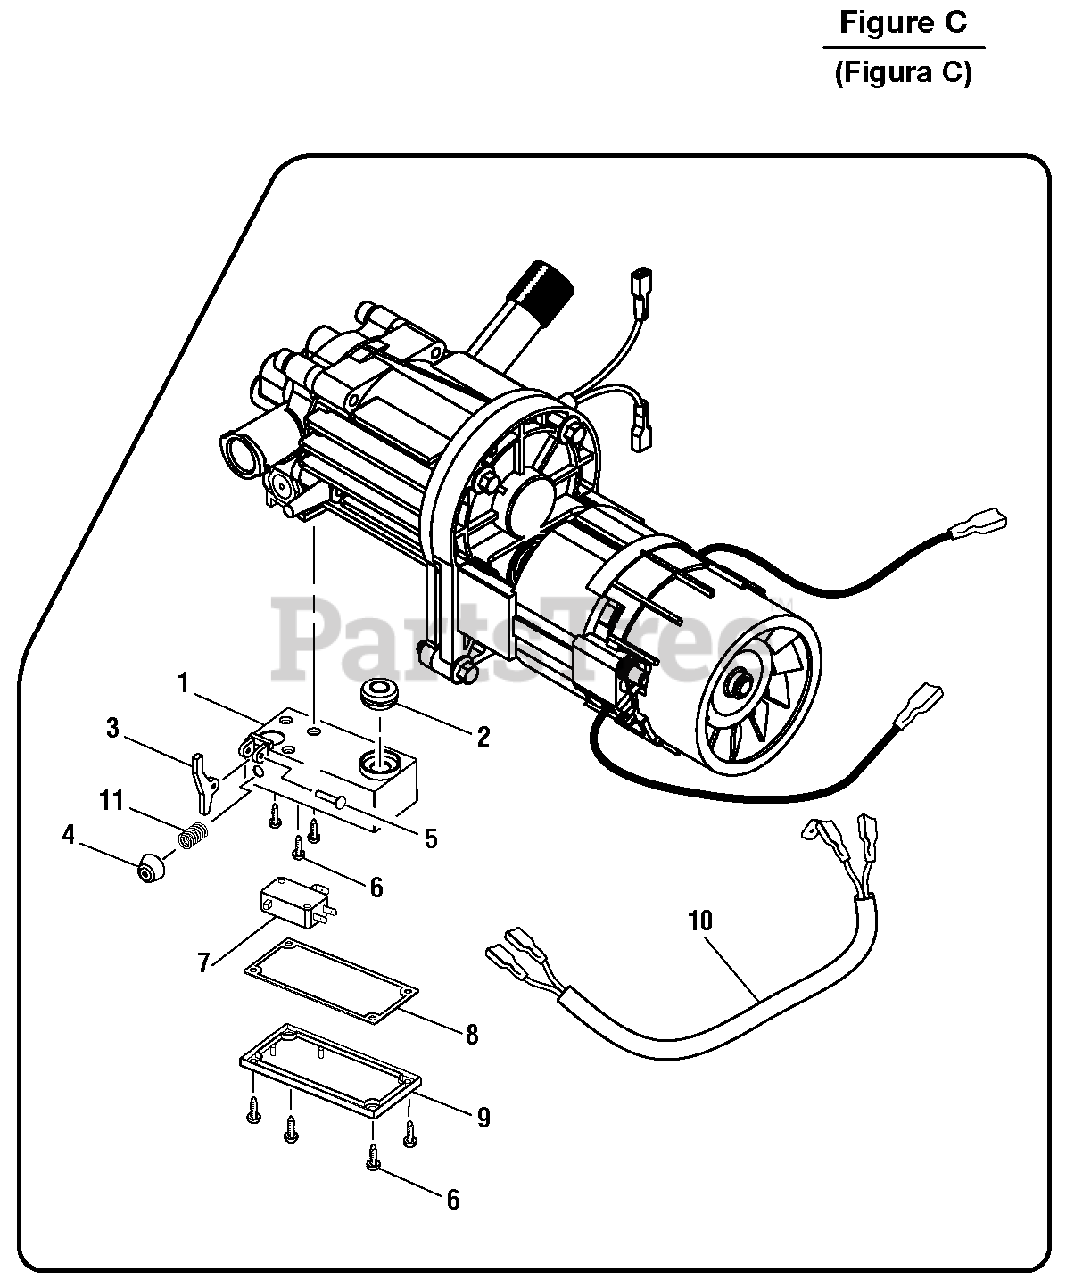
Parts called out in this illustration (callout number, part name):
1	Switch Box
3	Stop Switch Lever
4	Switch Box Seal
5	Stop Switch Lever Pin
6	Screw (2.9 x 10 mm)
7	Stop Switch
8	Switch Box Gasket
9	Switch Box Cover
10	Stop Switch Wiring Harness Assembly
11	Compression Spring
